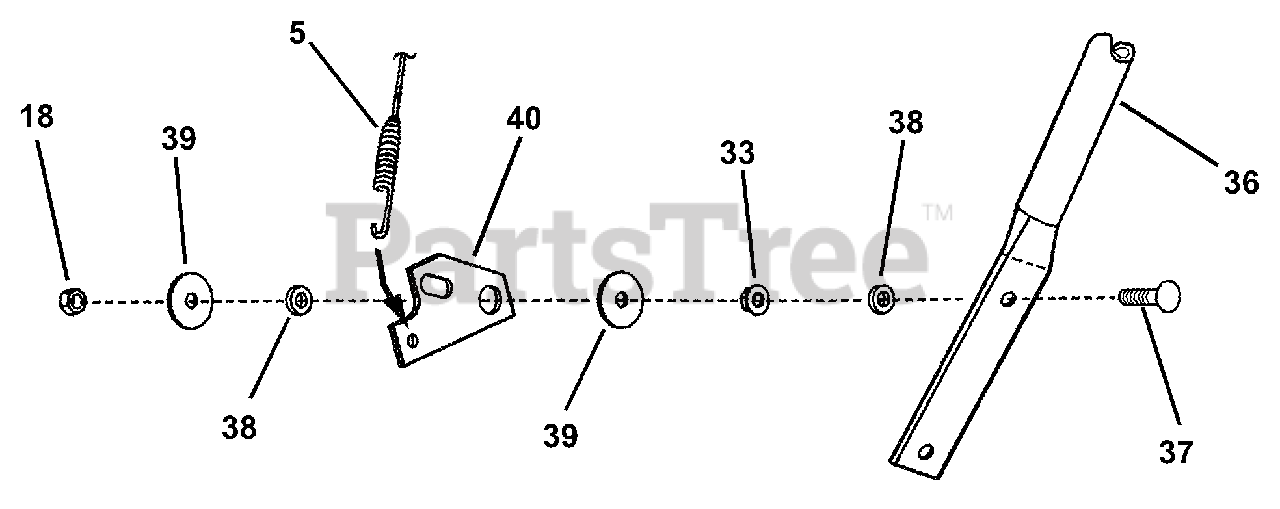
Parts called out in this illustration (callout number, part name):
5	CABLE, Clutch
18	NUT, 5/16-18 Hex Center Lock, Grade B
33	NUT, 5/16-18 Hex Flange Lock, Grade 5
36	HANDLE BAR, Lower
37	BOLT, 5/16-18 x 1-1/2", Square Neck Carriage, Grade 5
38	SPACER, 5/16"
39	WASHER, 5/16" Flat
40	LEVER, Clutch
